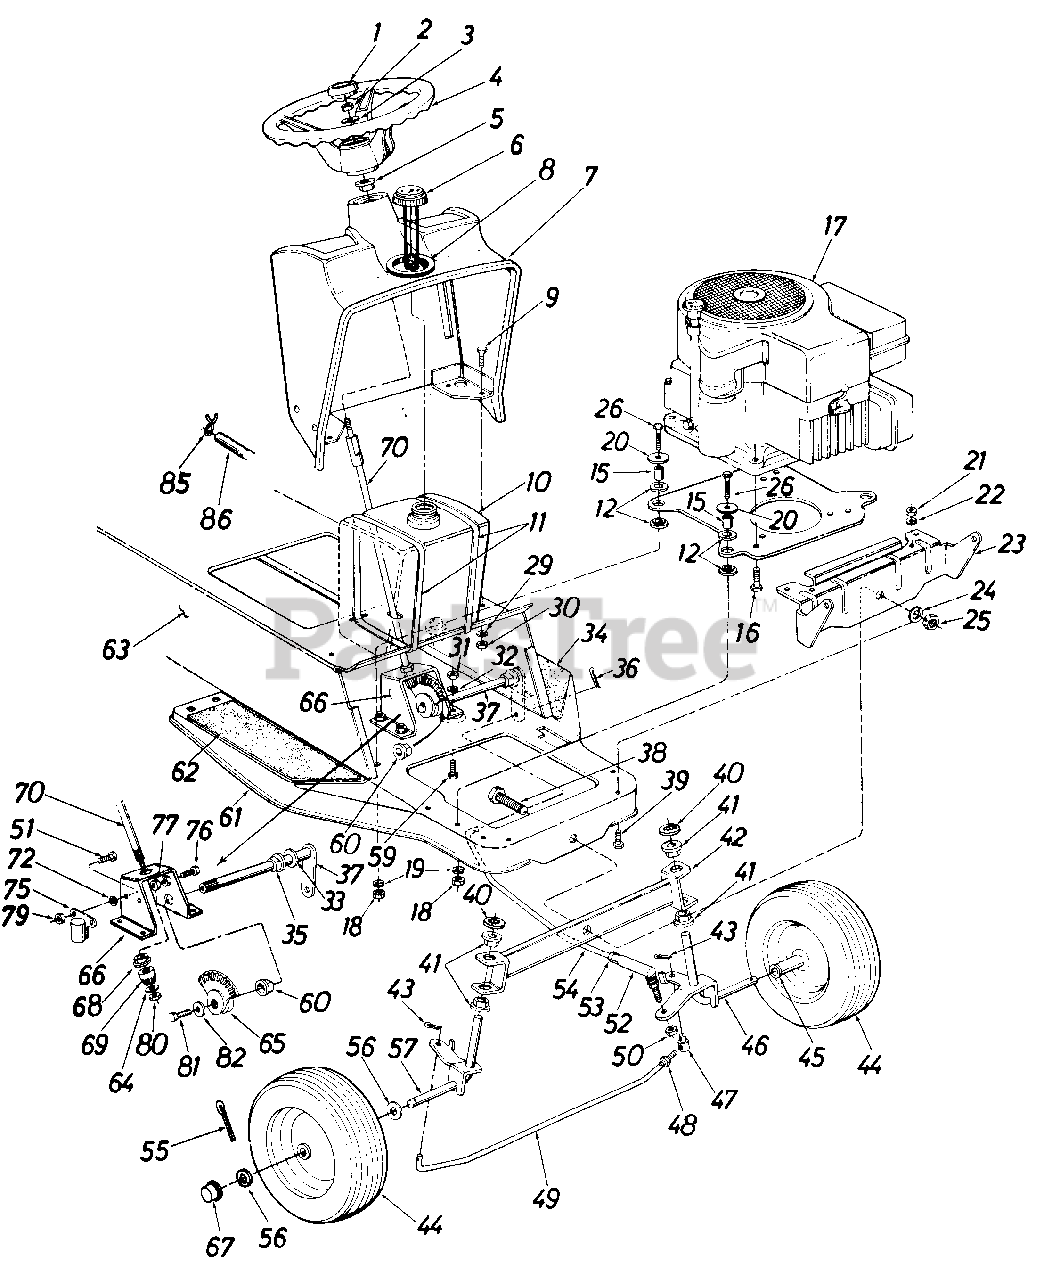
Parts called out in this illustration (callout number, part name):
1	Steering Wheel Cap
2	Hex Cent. L-Nut 5/16-18 Thd.
3	Bell-Wash. .345 I.D. x .88 O.D.
4	Steering Wheel
5	Hex Flange Bushing .63" 1. D.
6	Fuel Gauge-Cap
7	Dash Panel Ass'y. w/Headlights
8	Rubber Grommet
9	Hex Sems Scr. 1/4-20 x .75" Lg.
10	Fuel Tank
11	Cable Tie
12	Engine Mounting Grommet
15	Spacer
16	Hex Wash. Hd. Self-Tap Screw 3/8-16 x 1.25" Lg.
17	Engine
18	Hex Nut 5/16-24 Thd.
19	L-Wash. 5/16" Scr.
20	Fl-Wash. .34" I.D. x 1.12" O.D. x .125
21	Hex Nut 5/16-18 Thd.
22	L-Wash. 5/16" Scr.
23	Front Pivot Bracket
24	L-Wash. 5/8" Scr.
25	Hex Cent. L-Nut 5/8-18 Thd.
26	Hex Scr. 5/16-24 x 1.25 H.T.
29	L-Wash. 1/4" Scr.
30	Hex Nut 1/4-20 Thd.
31	Hex Nut 5/16-18 Thd.
32	L-Wash. 5/16" Scr.
33	Fl-Wash. .812 I.D. x 1.38 O.D. x .100
34	Foot Pad-L.H.
35	Flange Brg. w/Flats
36	Cotter Pin 3/32" Dia. x .75" Lg .
37	Steering Arm Ass'y.
38	Hex Scr. 5/8-18 x 1.62" Lg.
39	Hex Sems Scr. 5/16-18 x .75" Lg.
40	Push Nut
41	Hex Flange Bushing .62" 1. D.
42	Pivot Bar Ass'y.
43	Cotter Pin 1/8" Dia. x .75" Lg.*
44	Ass'y. Comp.-Pneumatic
45	Flange Bearing
46	Fron t Axle Ass'y.-L. H .
47	Pivot Bushing
48	Hex Jam Nut 3/8-24 Thd.*
49	Tie Rod
50	Hex Ins. L-Nut 3/8-24 Thd.
51	Hex Scr. 1/4-20 x .50" Lg.*
52	Ball Joint Ass'y.
53	Hex Jam Nut 3/8-24 Thd.*
54	Drag Link
55	Cotter Pin 1/8" Dia. x 1.25" Lg.*
56	Fl-Wash. .630 I.D. x 1.120 O.D. x .100
57	Front Axle Ass'y.-R.H.
59	Hex Sems Scr. 5/16-18 x .75" Lg.*
60	Flange Brg. w/Flats
61	Front Frame Ass'y.
62	Foot Pad-R.H.
63	Rear Frame
64	Fl-Wash. 5/16" Scr.
65	Side Gear
66	Steering Gear Support Ass'y.
67	Hub Cap
68	Hex Flange Bushing .50" I.D.
69	Pinion Gear
70	Steering Shaft
72	Ext. L-Wash. 1/4" Scr.*
75	Solenoid
76	Hex Scr. Nylon 3/8-16 x 1.25" Lg.
77	Hex Cent. L-Nut 3/8-16 Thd.
79	Hex Nut 1/4-20 Thd.*
80	Hex Cent. L-Nut 5/16-24 Thd.
81	Hex Scr. 3/8-24 x .75" Lg.*
82	Bell-Wash.
85	Hose Clamps
86	Fuel Line 13" Lg.
